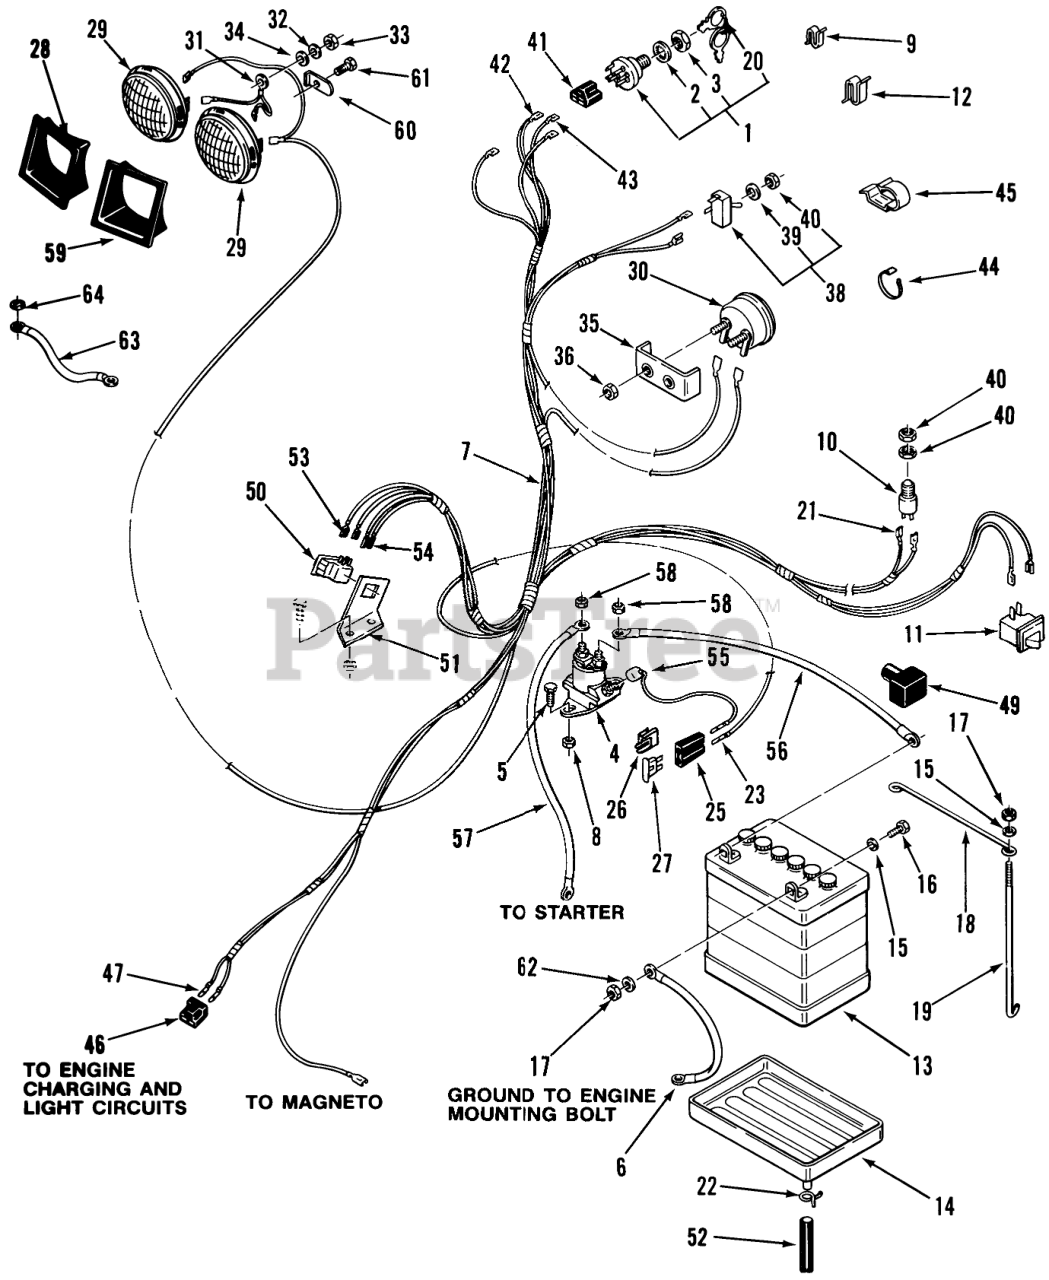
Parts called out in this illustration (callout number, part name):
1	ASSY-SWITCH IGNITION
2	LOCKWASHER
4	Solenoid
5	Screw
6	Wire
7	Wiring Harness Assy
8	Nut
9	SPEED CLIP
10	SWITCH-SEAT
11	SWITCH INTERLOCK
12	CLIP
13	Battery
14	TRAY-BATTERY
16	Bolt
17	Nut
18	ROD-HOLD DOWN
20	Key-EL
21	Connector
22	Clamp
23	TERMINAL-FUSE
25	AUTO-FUSEBLOCK TERM
27	FUSE-BLADE, 15 AMP
28	BEZEL-HEADLIGHT, RH
29	HEADLAMP
30	AMMETER W/CLAMP
31	LIGHT GROUND WIRE
32	Washer-Lock
33	Nut
34	WASHER 5/16 SAE
35	Clamp
36	HEX NUT 10-32 E.S.
38	SWITCH-LIGHTS
39	TAB-WASHER
40	NUT-HEX, SPECIAL
41	CONNECTOR-5 WAY-SERV
42	TERMINAL-TAB RCPT
43	Terminal
44	PLASTIC TIE
45	CLIP-WIRE
46	Conn Body Part of 7
47	Terminal
49	Boot
50	PTO Interlock Switch
51	BRACKET-SWITCH (NS)
52	TUBE-BATTERY DRAIN
53	Terminal
54	Wire Terminal (Part of 1)
55	Terminal Part of 5
56	Cable
57	Starter To Solenoid Cable 16.0 in. (40.6 cm) 216-5 Only
57	Wire
58	Nut
59	BEZEL-HEADLIGHT, LH
60	LOCK-HEADLIGHT
61	Bolt
62	Washer
63	WIRE GROUND
64	Washer-Lock
